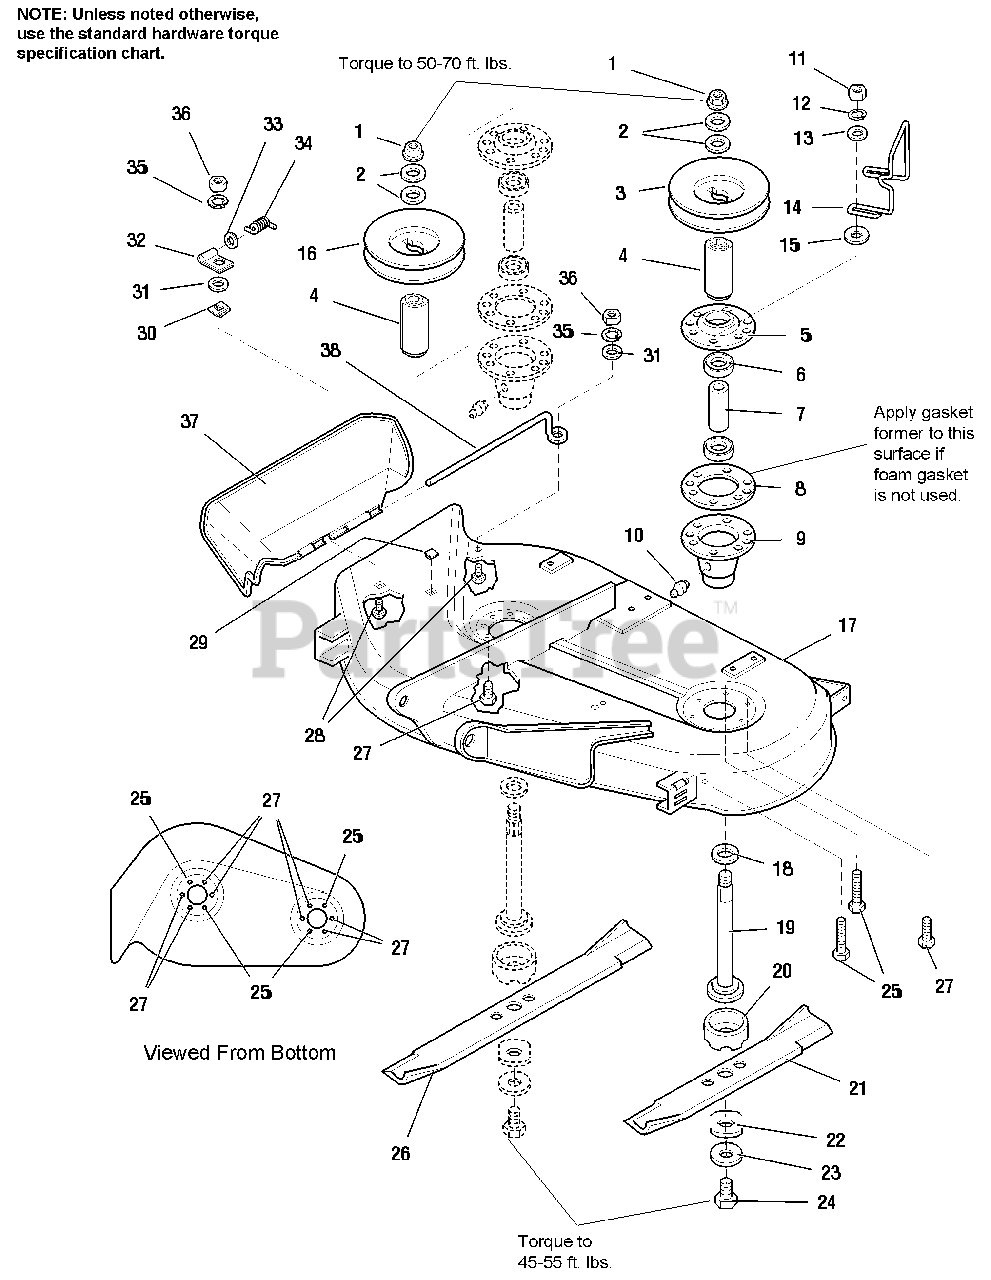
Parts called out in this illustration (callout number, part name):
1	NUT, Hex Flange, 9/16-8
2	WASHER, Belleville
4	HUB ADAPTER, Pulley
5	COVER, Arbor Housing
8	GASKET, Foam
9	HOUSING ASSEMBLY, Arbor Bottom, w/Lube Fitting
10	FITTING, Grease
11	NUT, Hex, 5/16-18 (Early Models)
11	NUT, Hex, Whizlock, 5/16-18 (Later Models)
12	LOCKWASHER, 5/16 (Early Models)
13	WASHER, Flat, 5/16
15	WASHER, 3/8
17	MOWER DECK HOUSING, 38" (Orange)
17	MOWER DECK HOUSING, 38" (Charcoal Grey)
17	MOWER DECK HOUSING, 38" (Red)
19	SHAFT, Arbor
20	SHIELD, Grass, Lower
21	BLADE, Mower, 16-1/8", LH
22	WASHER, Hex
23	WASHER, Spring
24	CAPSCREW, Hex, Head, 7/16-14 x 1-1/4
25	CAPSCREW, Taptite, 5/16-18 x 1-3/4
26	BLADE, Mower, 22-1/4", RH
27	CAPSCREW, Taptite, 5/16-18 x 3/4
28	CARRIAGE BOLT, 1/4-20 x 7/8
28	CARRIAGE BOLT, 1/4-20 x 1-1/4 (Export Models)
30	NUT, Push
31	WASHER, Plain (6 Total for Export Models)
33	WASHER, 5/16
36	NUT, Hex, 1/4-20 UNC ESNA
37	DEFLECTOR, Plastic
38	ROD, Deflector, Front
39	COVER ASSEMBLY LH, Arbor (Export Models)
40	CAPSCREW, Hex Head Taptite, 5/16-18 x 3/4 (Export Models)
41	COVER ASSEMBLY R H , Arbor (Export Models)
